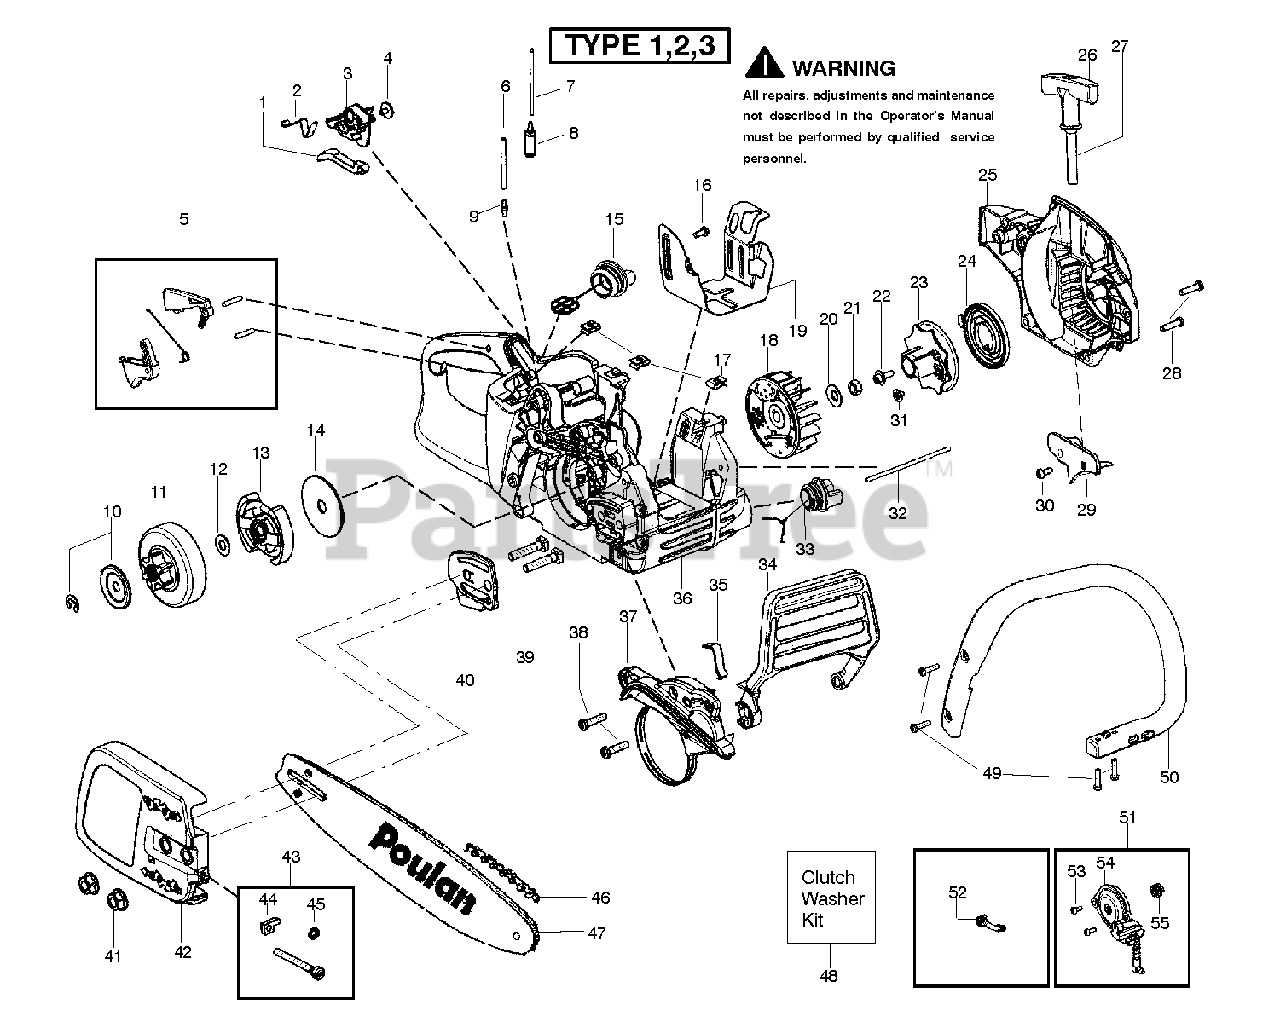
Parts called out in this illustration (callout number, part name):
1	KNOB CHOKE
2	SPRING IGNITION SWITCH
3	LEVER IGNITION SWITCH
5	KIT TRIG AND LOCKOUT
6	LINE KIT
7	KIT-LINE
8	ASSY FUEL PICK UP W/LINE
9	FUEL LINE FITTING
10	KIT SAS CLUTCH WASHER
11	ASSY CLUTCH DRUM 3/8
12	KIT SAS CLUTCH WASHER
13	ASSY CLUTCH
14	WASHER CLUTCH LARGE
15	FUEL CAP ASSY W/RET
18	ASSY FLYWHEEL
19	SHIELD HEAT
20	WASHER-FLYWHEEL
21	NUT-FLYWHEEL
23	STARTER PULLEY
24	SPRING STARTER
25	KIT FAN HSG PURPLE
26	HANDLE STARTER
27	KIT-ROPE
28	SCREW M5.38-14X22.225MM
29	BAFFLE FAN HOUSING
30	SCREW 6-19X.437
32	ASSEMBLY-OIL-VENT
33	OIL TANK CAP
34	HANDGUARD
35	SPRING HANDGUARD
36	ASSEMBLY CHASSIS GREEN EVAP
37	KIT CHAIN BRAKE
38	SCREW M5.38-14X22.225MM
40	PLATE BAR MOUNTING
42	ASSY CLUTCH COVER PURPLE
43	RETAINER
44	ADJUST PIN,BAR 36/41
45	RETAINER
46	CHAIN 18" 91VJ 62DL 3/8 .050
48	KIT SAS CLUTCH WASHER
49	SCREW M5.38-14X22.225MM
50	HANDLE FRONT
51	KIT OIL PUMP
52	ASSY PICK UP OIL TANK
53	SCREW 6-19X.437
54	ASSY OIL PUMP
55	WORM GEAR
